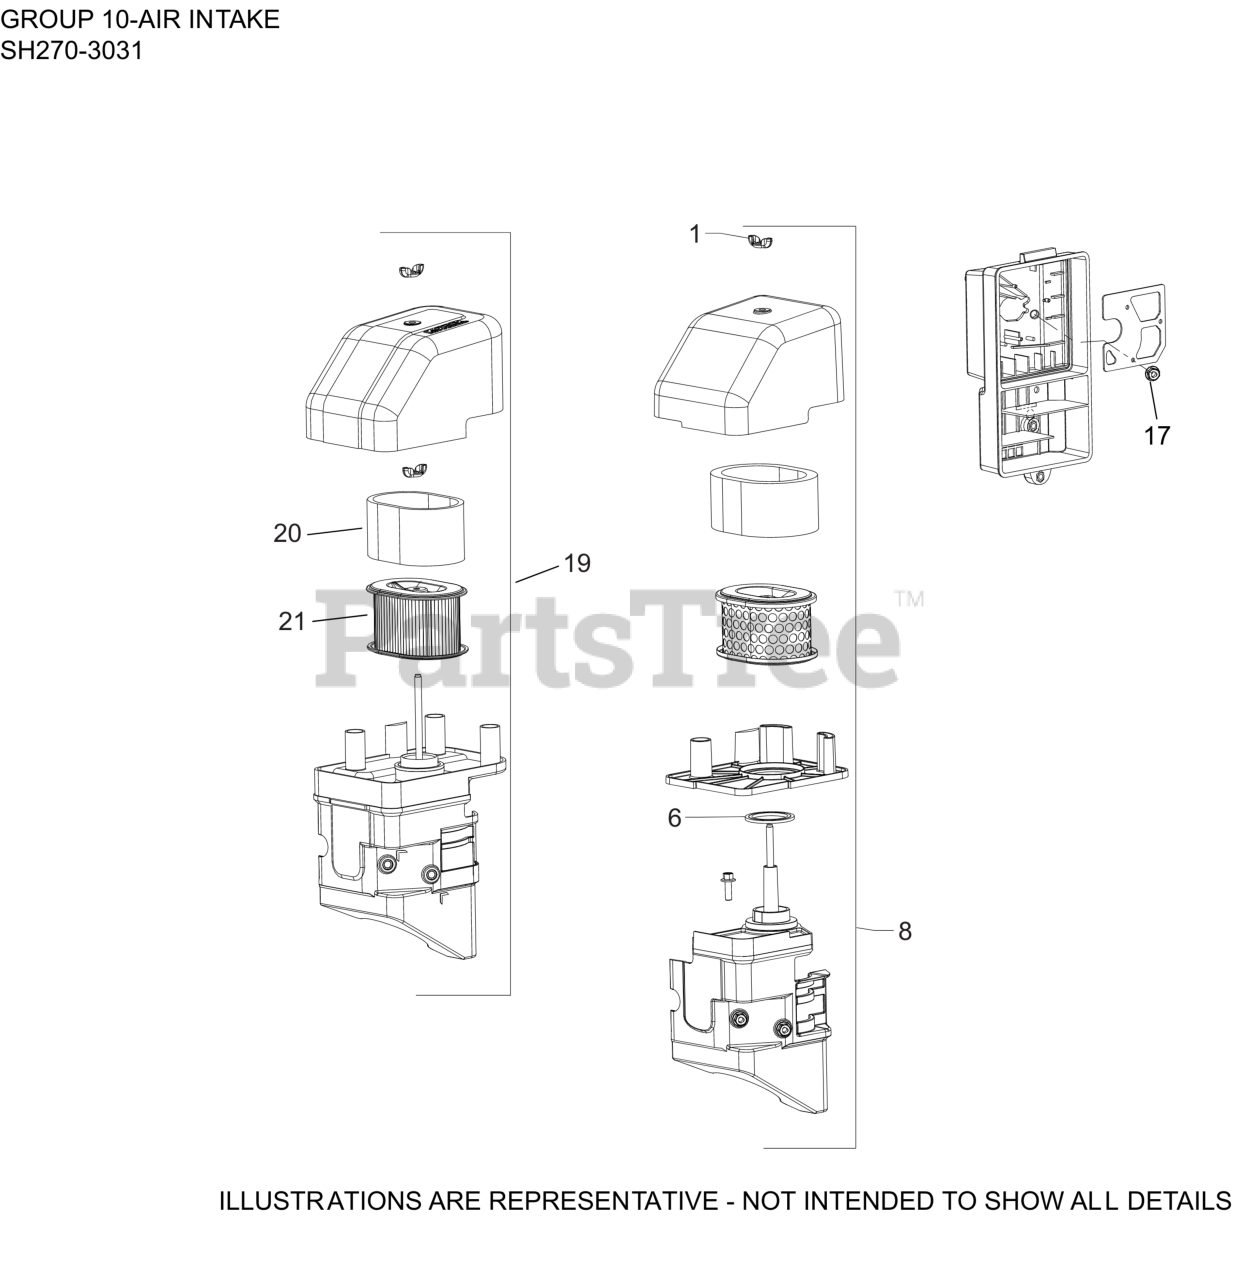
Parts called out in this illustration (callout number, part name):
1	NUT, WING
6	GASKET, AIR FILTER
8	AIR CLEANER, COVER ASSY-(#1804809S)
17	NUT, HEX FLANGE LOCK (M6)
19	KIT, AIR CLEANER
20	ELEMENT, PRE-CLEANER
21	ELEMENT, AIR FILTER-USE 18 083 23-S
